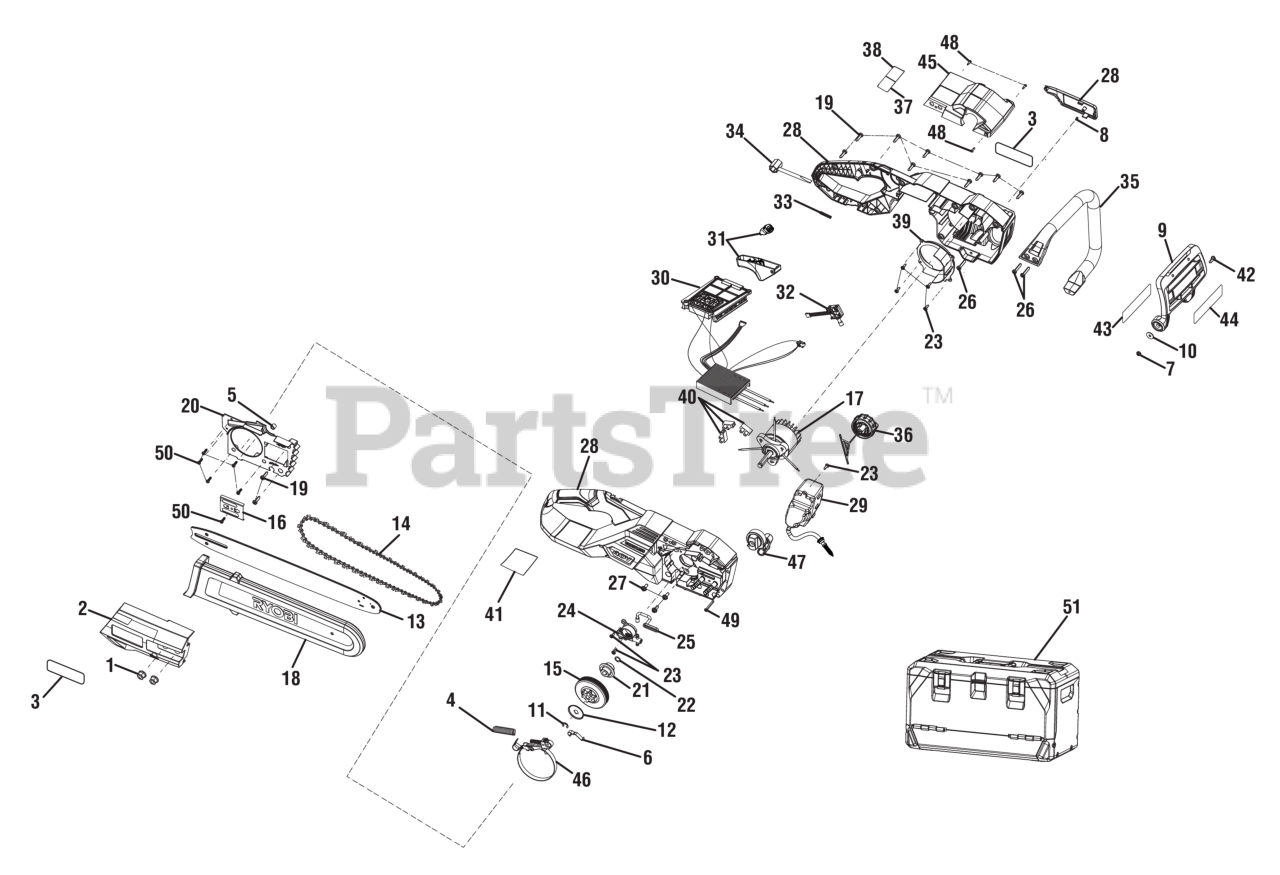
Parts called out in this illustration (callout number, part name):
1	Hex Nut (5/16-18 Flange)
2	Sprocket Cover Assembly (Inc. Key No. 3)
3	HP Logo Label
5	Hand Guard Insert
8	Screw (M3 x 8 mm, Pan Hd., Pan Hd)
9	Guard Assembly (Inc. Key Nos. 43-44)
10	Washer (ID5.2 x OD16 x 1.5t)
12	Washer (Special)
13	Bar (18 in.)
14	Chain (18 in.)
15	Sprocket w/ Drum
16	Guide Bar Plate Assembly
19	Screw (T20 x 15 mm)
20	Cover Housing
21	Oil Pump Drive
23	Screw (M4.2 x 12 mm, T20 Torx Pan Hd.)
25	Oil Output Tube
26	Screw (M5 x 25 mm, T25 Torx Pan Hd.)
27	Screw, T25, M5X8, Steel, Black ZincePlat
28	Housing Assembly (Inc. Key Nos. 3 & 41)
29	Oil Tank Assembly
30	Motor Controller, Switch & Battery Connector Assembly
31	Switch Trigger & Lock Out Button Assembly
33	Compression Spring (Trigger Lock)
35	Front Handle
36	Oil Tank Cap Assembly
37	Icon Label (Right)
38	Icon Label (Left)
39	Volute Cover
40	Terminal Block w/Screw
41	Data Label
42	Screw (M5 x 15 mm, T25 Torx Hd.)
43	Warning Label
44	40V Brushless Logo Label
45	Top Cover Assembly (Inc. Key Nos. 37-38)
46	Brake Band Assembly
47	Chain Brake Assembly
48	Screw (M3 x 10 mm)
49	Screw (M4-18 x 30 mm, T15 Torx Soc. Hd.)
50	Screw, T20, M4-18X12, Low Carbon Steel,
51	Carry Box
